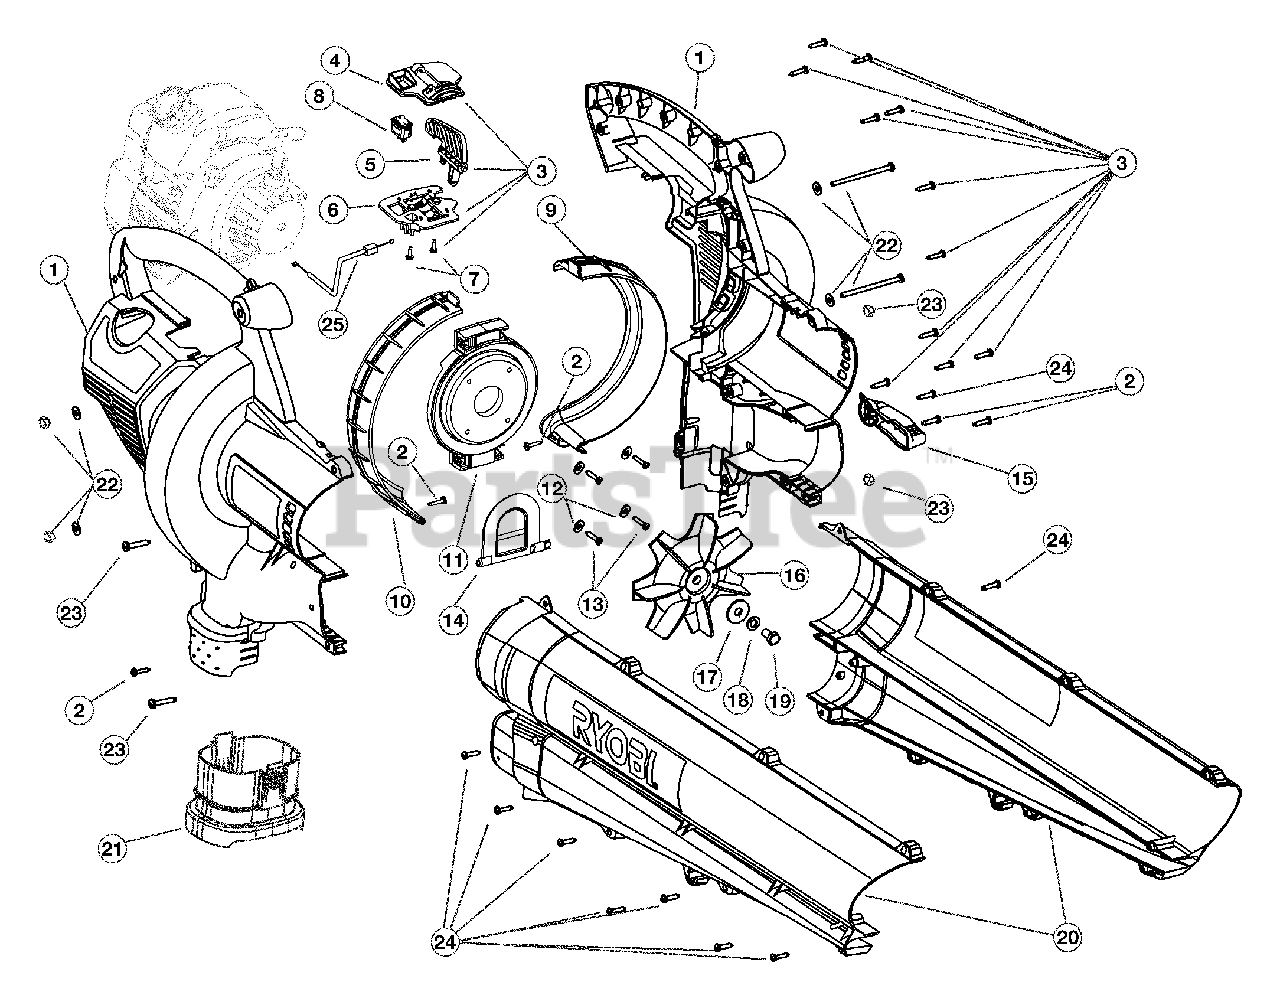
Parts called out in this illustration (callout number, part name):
1	Engine Cover Assembly
2	Cover Screw
3	Throttle Control Assembly
4	Upper Throttle Control Plate
5	Throttle Control Lever
6	Lower Throttle Control Plate
7	Screw, Plastic
8	Rocker Switch Assembly
9	Left Side Liner
10	Right Side Liner
11	Engine Mounting Plate
14	Mode Control Flapper
15	Mode Control Lever
16	Impeller Blade
17	Washer
18	Lock Washer
20	Blower/Vac Tube Assembly
21	Vacuum Bag Adapter
22	Mounting Plate Hardware
23	Blower/Vac Tube Mounting Hardware
25	Throttle Cable
